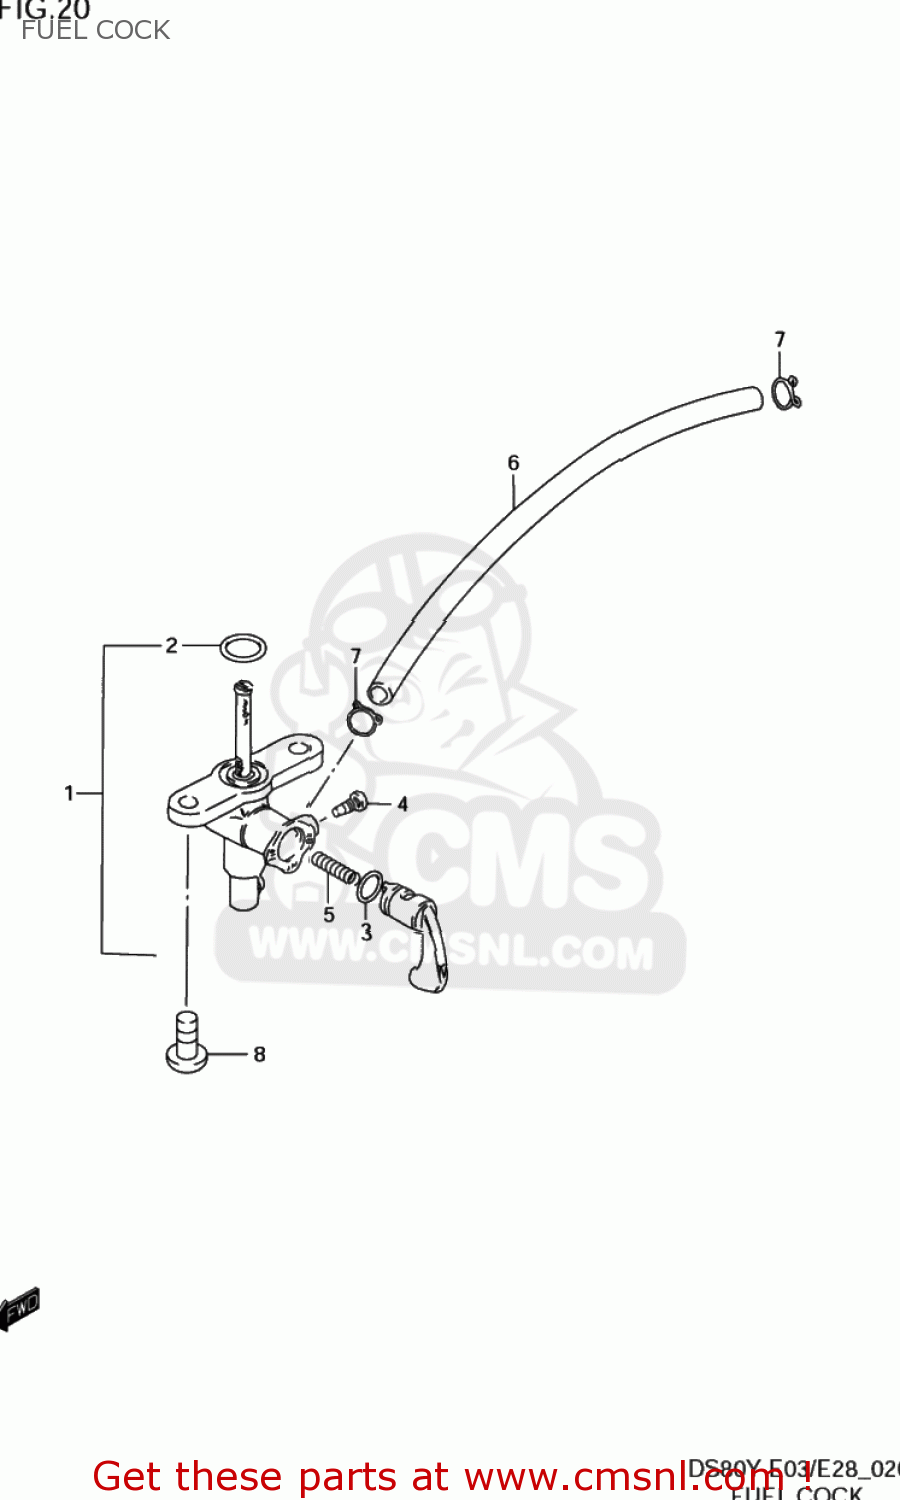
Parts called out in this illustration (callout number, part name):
1	COCK ASSY,FUEL
2	O RING
3	O RING,LEVER
4	SCREW
5	SPRING
6	HOSE(5X8.2X600)
7	CLIP
8	SCREW
